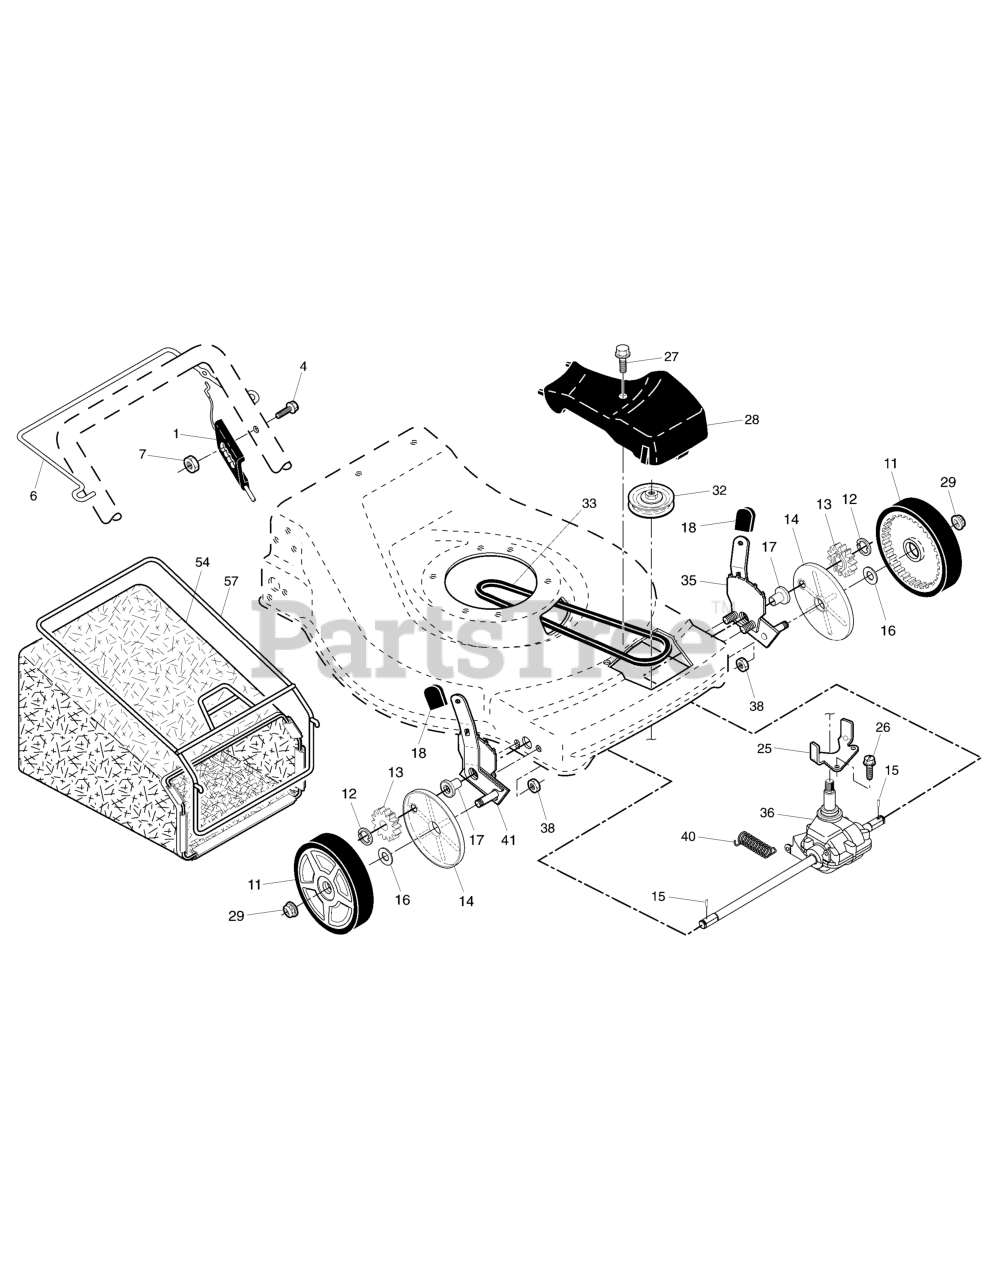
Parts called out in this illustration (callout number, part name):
1	Drive Control Assembly (Includes Cable)
4	Screw, Hex Washer Head
6	Bar, Drive Control
7	Nut, Hex Flange Lock
11	Wheel & Tire Assembly, Front
12	E-Ring
13	Pinion
14	Dust Cover
15	Pawl, Drive
16	Washer, Flat 3/8
17	Bearing, Wheel Adjuster
18	Selector Knob
25	Belt Keeper
26	Screw, Hi-Lo Thread, #12 x 5/8
27	Pan Head Tapping Screw #10-24 x 2-3/4
28	Drive Cover
29	Locknut, Hex
32	Drive Pulley
33	V-Belt
35	Kit, Wheel Adjuster, LH (Includes Knob & Bearing)
36	Gear Case Assembly, Complete
38	Locknut, Hex 1/4-20
40	Spring
41	Kit, Wheel Adjuster, RH (Includes Knob & Bearing)
54	Grassbag Assembly
57	Frame, Grassbag
